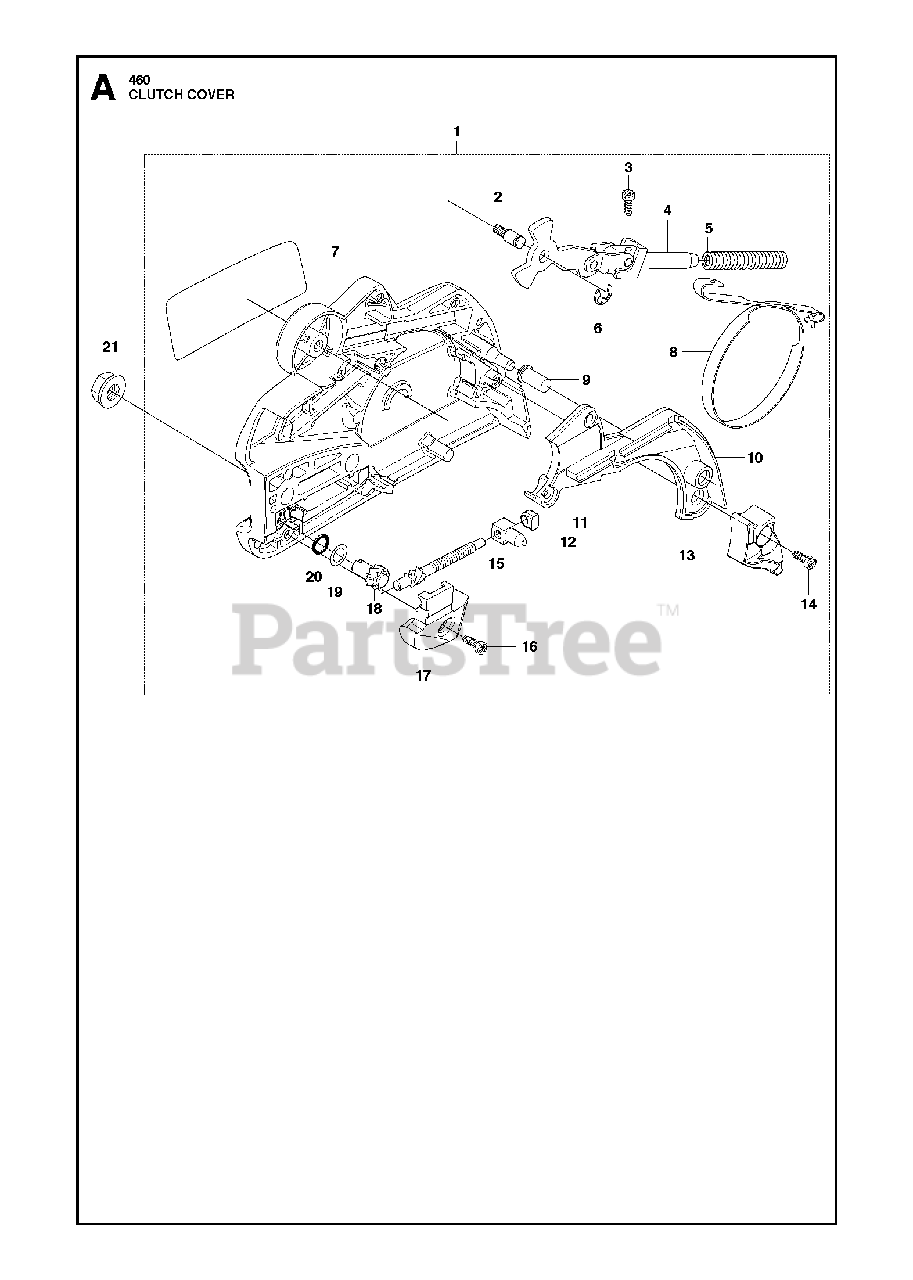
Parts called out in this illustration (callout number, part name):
1	CLUTCH COVER
2	PIN
3	SCREW
4	JOINT
5	SPRING
6	E-RING 4
7	DECAL, CLUTCH COVER
8	BRAKE BAND
9	SLEEVE
10	COVER
11	SLEEVE
12	PAWL
13	PROTECTOR
14	SCREW
15	SCREW
16	SCREW
17	COVER
18	WORM WHEEL
19	WASHER
20	O-RING
21	NUT M8 FLANGE
